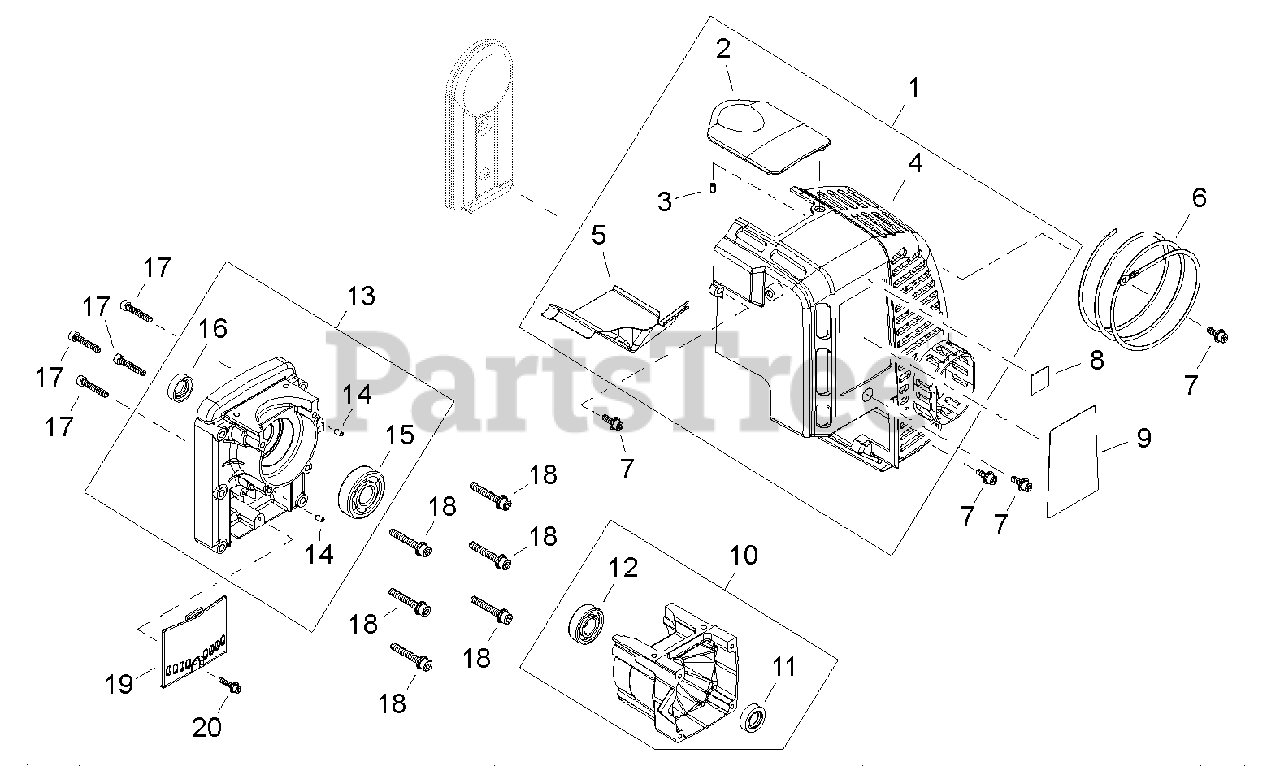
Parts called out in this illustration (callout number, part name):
1	COVER ASSY, ENGINE
2	COVER, SPARK PLUG
3	PIN, SPRING 4×8
4	COVER, ENGINE
5	HEAT SHIELD, EXHAUST
6	WIRE, STATIC DISCHARGE 1050 MM
7	BOLT M5×16
8	LABEL, CAUTION - HOT
9	LABEL, EB8520
10	CRANKCASE ASSY, S
11	SEAL, OIL 21
12	BEARING, BALL 6202C3
13	CRANKCASE ASSY, M
14	PIN, LOCATING Ø4×8
15	BEARING, BALL 6303 C3
16	SEAL, OIL 21
17	BOLT 5×30
18	BOLT, ADHESIVE M6×40
19	COVER, DUST
20	BOLT M4×20
